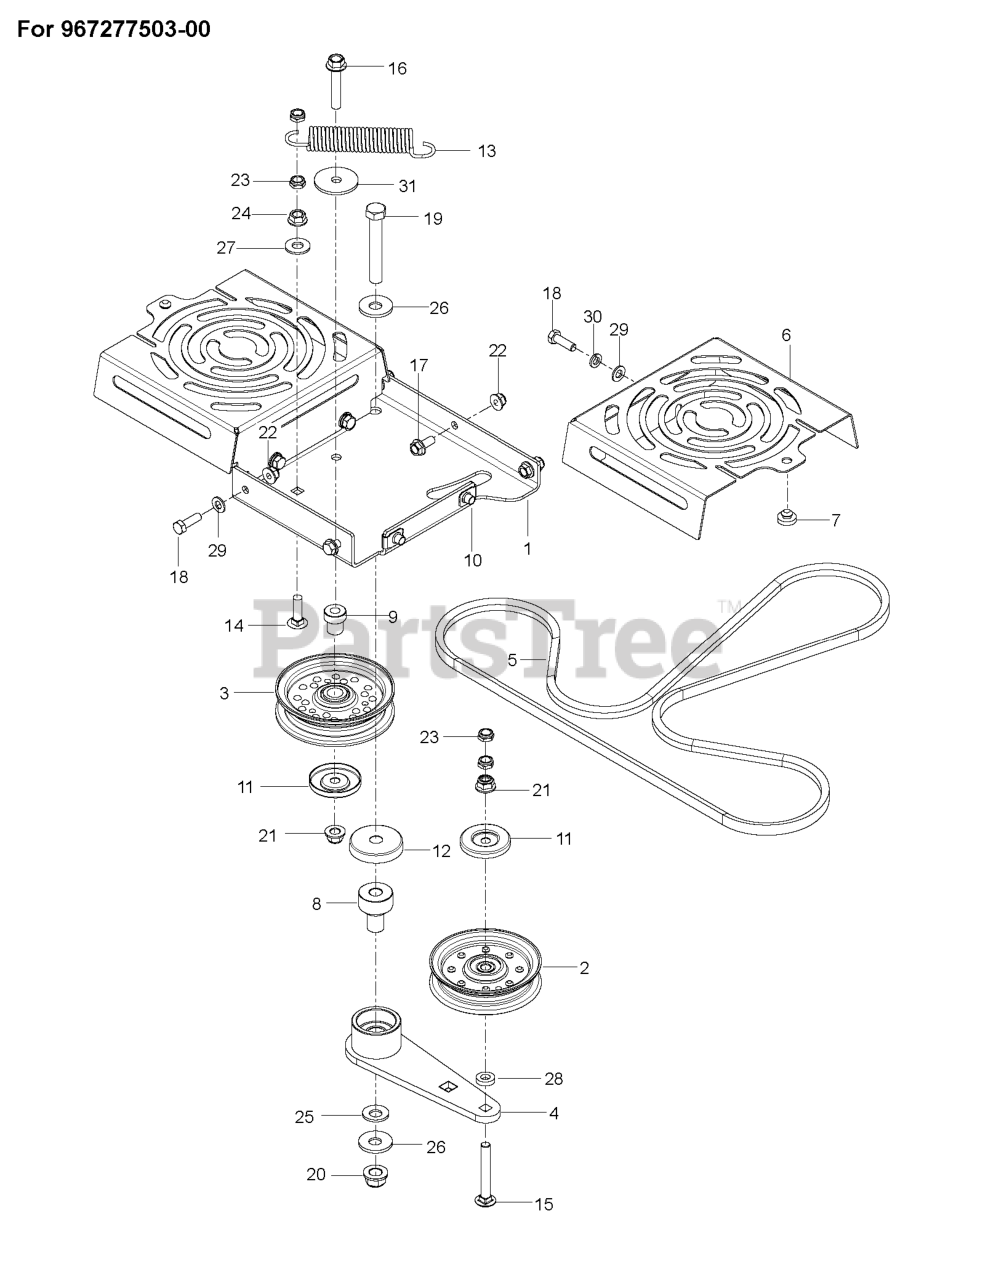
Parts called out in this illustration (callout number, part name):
1	PLATE.PNT.IDLER.SUPPORT.E-DIP
2	IDLER PULLEY
3	PULLEY.IDLER.FLAT.46.PR.DR.
4	ARM, IDLER, STEEL, W/BGS
5	BELT, HYDRO, 3400
6	SHIELD FAN BLACK
7	GROMMET, BUMPER
8	PIVOT, BEARING
9	PIVOT, IDLER
10	U-CLIP 5/16-18 NUT RETAINER
11	DUST SHIELD
12	SHIELD, DUST
13	SPRING, PUMP
14	BOLT.3/8-14X1.25
15	RHSNB 3/8-16 X 2.75
16	HHFS 3/8-16 X 2.0 GD 5
17	HHFS 5/16-18 X 3/4
18	HCS 5/16C X 1
19	HCS 1/2-13 X 3-1/4 GD 5 ZD
20	NUT, 1/2-13 HEX FLG NYLOC ZD
21	NUT 3/8-16 HEX FLG NYLOC ZD
22	5/16-18 NYLOC FLANGE NUT
23	NUT HEX 3/8-16 NYLON, THIN
24	NUT 3/8C WHIZ
25	CONTACT BELLSPR 1/2
26	WASHER.9/16 X 1 3/8 X 12 GA.
27	RP WASHER 3/8 FLAT
28	WASHER 3/8 X 3/4 X .187 TK
29	WASHER
30	WASHER.LOCK.HVY.HLCL.SPR.5/16
31	WASHER, 3/8 SPEC
